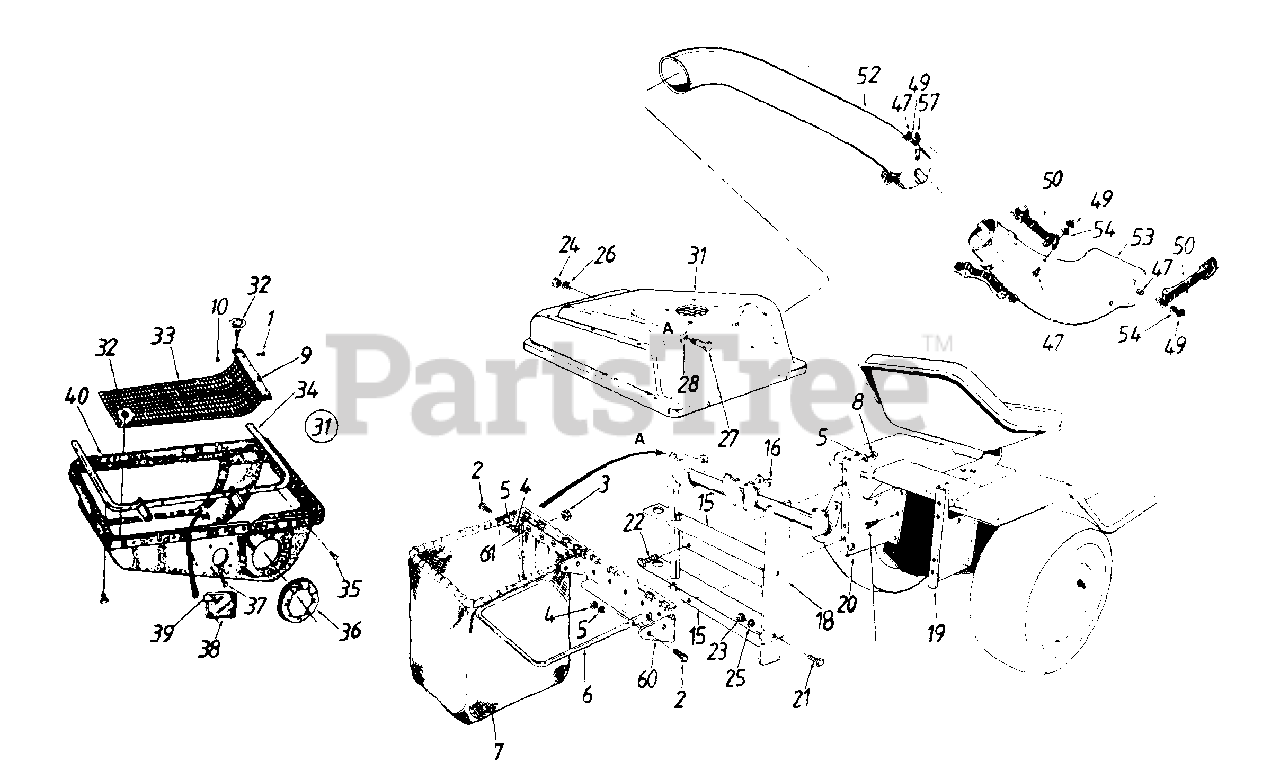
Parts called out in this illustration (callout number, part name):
1	Pop Rivet.188 Dia.
2	Hex Bolt 1/4-28 x .75
3	Hex Sems Nut #10-24 Thd.
4	Hex Nut 1/4-28 Thd.
5	L-Wash. 1 4" I.D.
7	Grass Catcher Bag
8	Hex Nut 1/4-20 Thd.
9	Screen Mtg. Brkt.
10	Flat Wash. 1/4" I.D.
16	Catcher Support Tube Ass'y.
18	Catcher Latch and Support Brkt.
22	Hex Bolt 1/4-20 x .62" Lg.- Grade 5
23	Hex Nut 5/16-18 Thd.
24	Hex Nut 3/8-16 Thd."
25	L-Wash. 5/16" I.D.
26	L-Wash. 3/8" I.D.
27	Shld. Bolt 3/8-16 x .50" Dia.
28	Bell-Wash..505" I.D. x 1.0" O.D.
31	Grass Catcher Cover Ass'y.
32	Twist Fastener
33	Screen
35	Hex AB-Tap Scr. 1/4 x .62"
37	Truss Mach. B-Tap Scr. #10 x .5" Lg.
38	Plastic Plate
39	Speed Nut
40	Grass Catcher Cover
47	Hex Bolt 1/4-20 x .5"
49	Hex Ins. L-Nut 1/4-20 Thd.
50	Retainer Strap Ass'y.
52	Catcher Tube
53	Discharge Chute
54	L-Wash..27" I.D.
57	Retainer Hook Brkt.
61	Truss Mach. Scr. #10-24 x .5" Lg.
